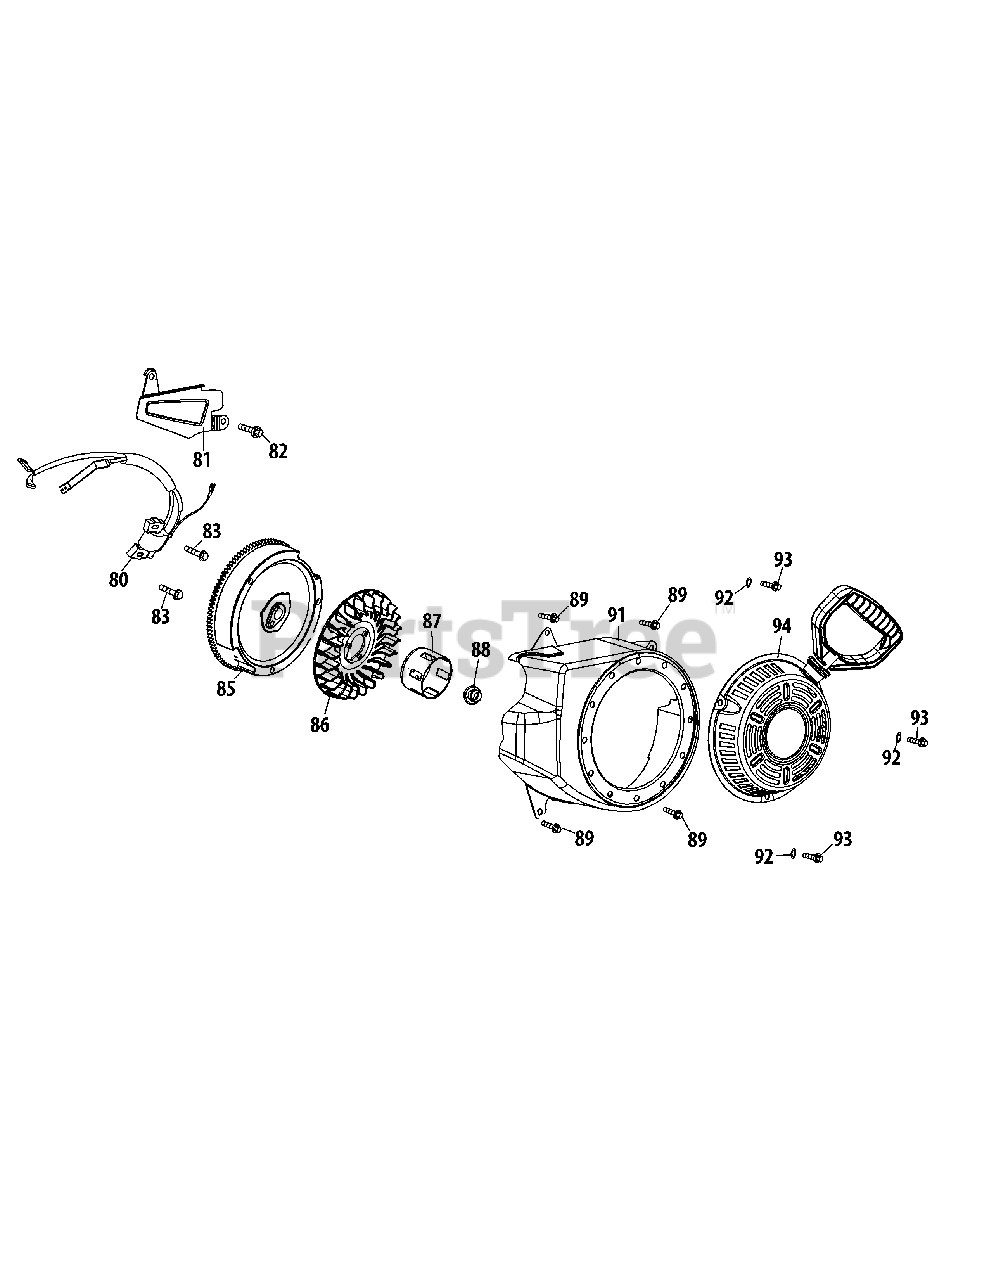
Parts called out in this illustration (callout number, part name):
80	Ignition Coil Assembly
81	Air Flow Shield
82	Bolt M6×10
83	Bolt M6×25
85	Flywheel
86	Cooling Fan
87	Starter Cup
88	Nut, Special, M14×1.5
89	Bolt M6×12
91	Blower Housing
92	Gasket 6
93	Bolt M6×10
94	Recoil Starter
